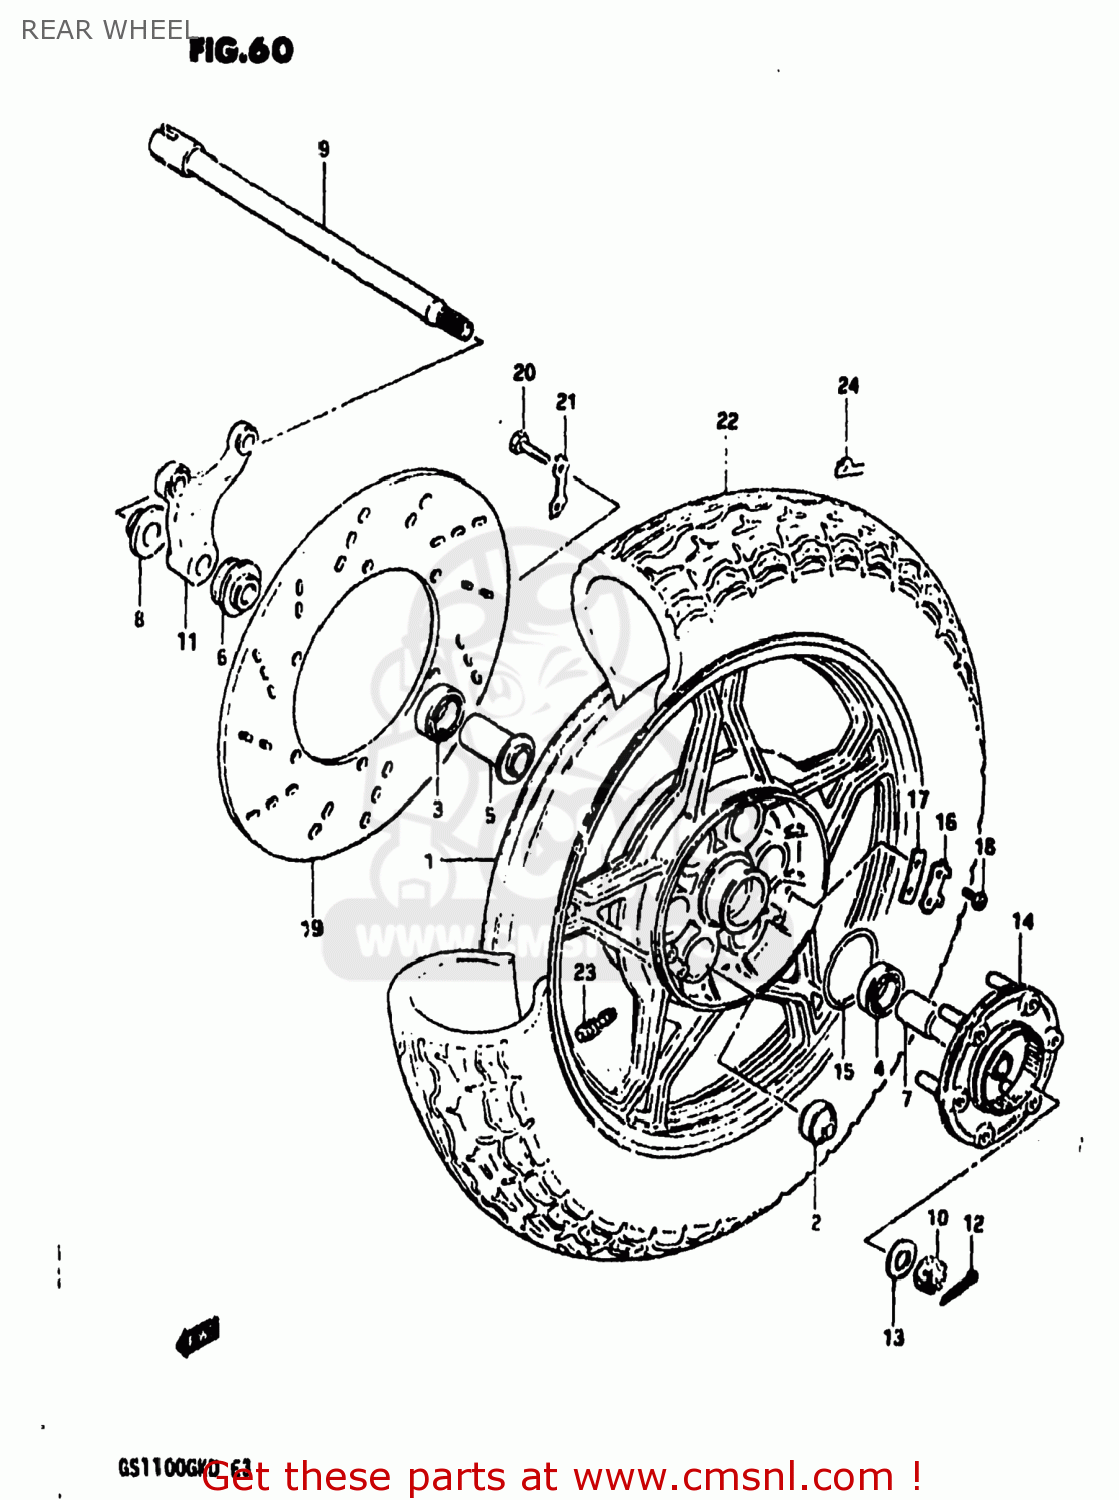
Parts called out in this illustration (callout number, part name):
1	CASTING WHEEL,REAR
2	BUSH
3	BEARING
4	BEARING
5	SPACER,REAR HUB BEARING
6	SPACER,REAR AXLE
7	SPACER,REAR AXLE,LEFT
8	SPACER,REAR AXLE,RIGHT
9	AXLE,REAR
10	NUT
11	BRACKET,RR,CALIPER
12	PIN,COTTER
13	WASHER (17.5X36X3.2)
14	JOINT ASSEMBLY,REAR HUB DRUM
15	O RING(D:2.1,ID:65)
16	WASHER
17	WASHER,THRUST(T:1.6)
18	BOLT(6X16)
19	DISC,RR BRAKE
20	BOLT(8X25)
21	WASHER
22	TIRE
23	VALVE ASSEMBLY,WHEEL RIM,J
24	BALANCER,WHEEL
